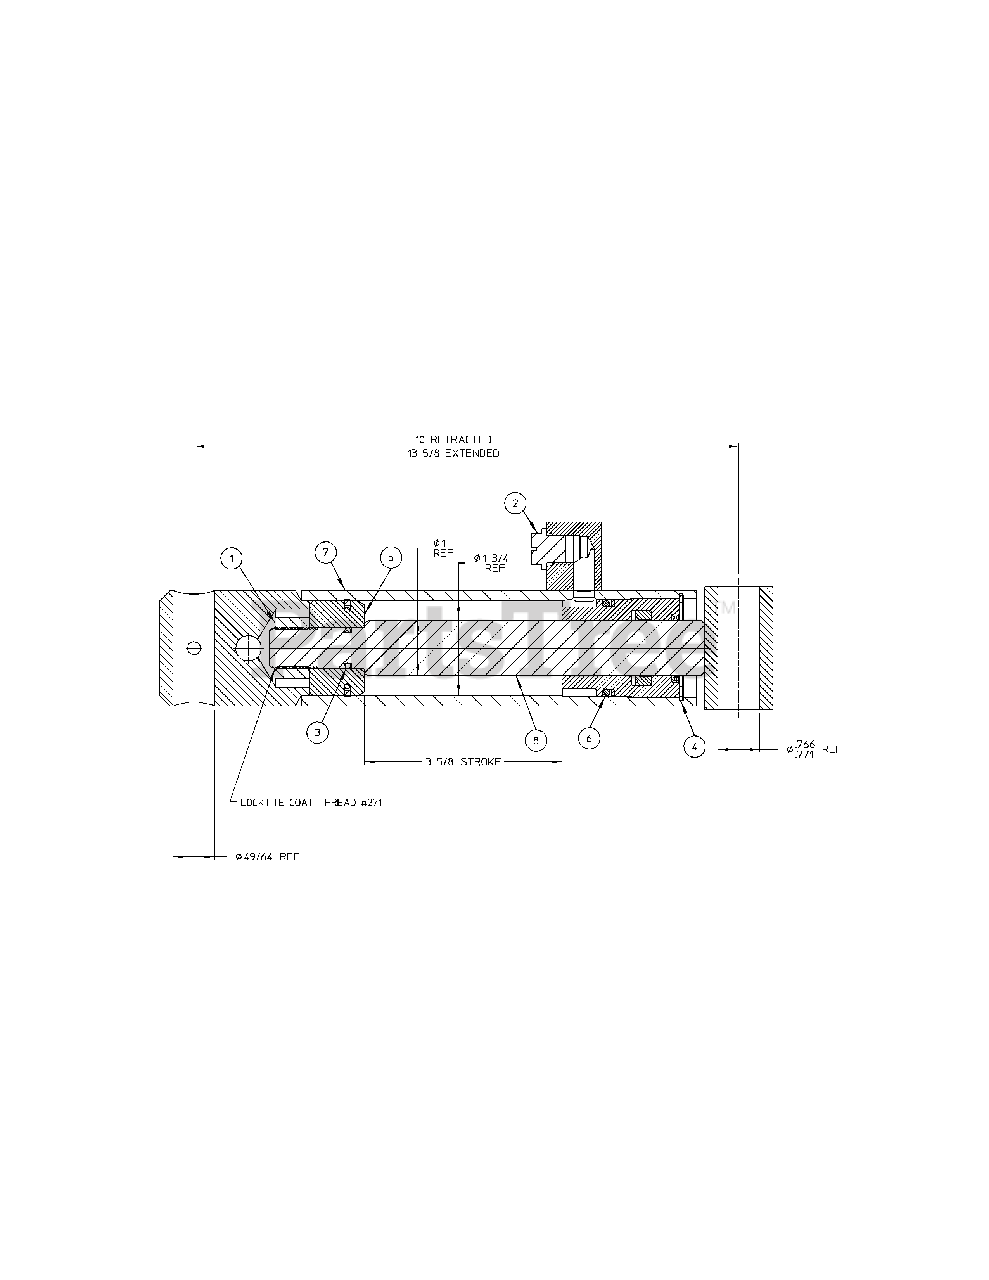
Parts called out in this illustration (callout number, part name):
1	Nut, Hex 3/4-16 GR 5 Lock
2	Cap Plug, 9/16-18 Thread with O-Ring
4	Retaining Ring
5	Piston Assembly
6	Gland Assembly
7	Cylinder Tube Weldment
8	Piston Rod Weldment
